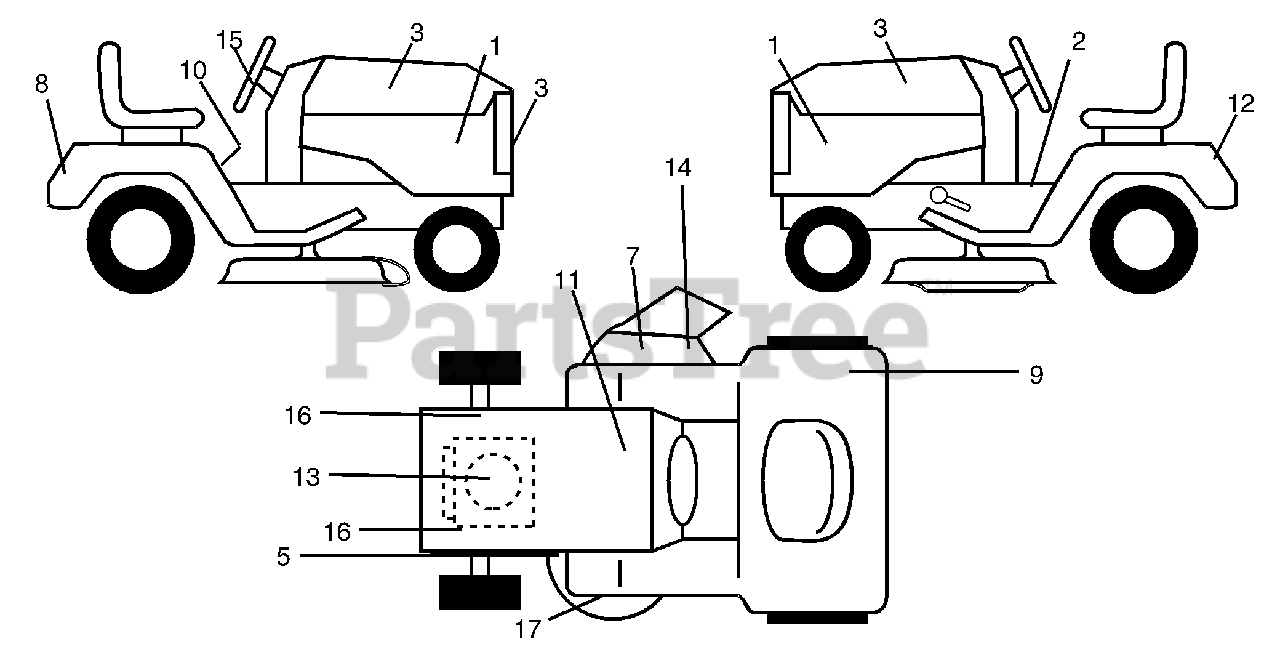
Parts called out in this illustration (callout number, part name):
1	Decal Hood Side Panel
2	Decal, Brake Parking Sandle
3	Decal, Hood, L. H. / R.H.
5	Decal, V-Belt Sch.
7	Decal, Mower Cutfinger Symbol
8	Decal, Logo, Fender
9	Decal, 100 DB/CE
10	Decal, Read Owners Manual
11	Decal, Bat Dan/Poi P/L Sym
12	Decal, Fender
14	Decal, Deck "B" 42"
15	Decal, Logo Steering Wheel Cap
16	Decal, Chassis Hot Muffler
17	Decal, Brake/Clutch Symbol LT
